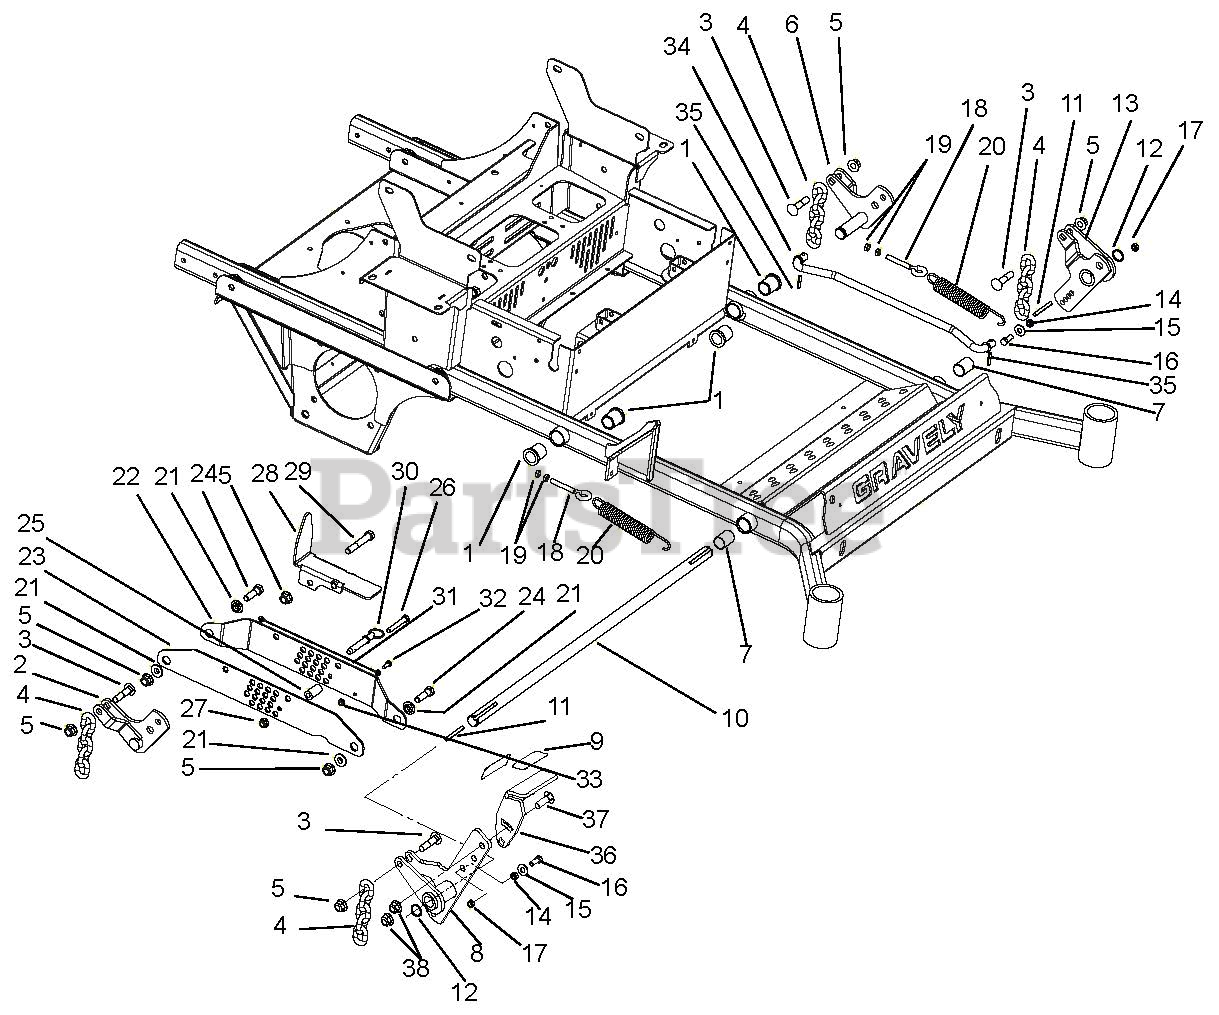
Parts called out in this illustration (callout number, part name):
1	BSHG-FLG 1.00X1.25X1.50X1.50
2	WMT, RH REAR DECK LIFT
3	BLT-RDHDSQNK .50-13X2.25 G5YZ
4	CHAIN, 5 LINK 3/8 MOWER LIFT
5	NUT-LK-NYL-FLG .50-13 YWZC
6	WMT, LH REAR DECK LIFT
7	BSHG,1.00ID X 1.125OD X 1.50LG
8	WMT, ADJUSTABLE DECK FOOT LIFT
9	GRIP, PEDAL 1.50 X 3.00
10	SHAFT, FRONT MOWER LIFT
11	KEY-SQ .25 X 2.50 X .25 SAE
12	RG-RTNG-EXT 1.00X.078
13	WMT, FRONT LH DECK LIFT
14	BSHG-SLV .377X.624X.235
15	WSHR-FL-STL.438X1.00X.083 YWZ
16	BLT-HEX .38-16X1.00 GR5 YWZC
17	NUT-LK-CTR-JAM .375-16 YWZC
18	BLT-EYE .375-16X2.50 YWZC
19	NUT-HEX-JAM .375-16 YWZC
20	SG-TENS .162X1.25X8.25 WLD 25
21	BSHG-FLG .515X.750X.395X1.120
22	RH LIFT/CUT HT BRKT-INBRD-BLK
23	RH LIFT/CUT HT BRKT-OUTBRD-BLK
24	BLT-HEX .50-13X1.75 GR5 YWZC
25	SPACER, .375 X .625 X 1.54
26	BLT-HEX .38-16X2.50 GR5 YWZC
27	NUT-LK-NYL-FLG .38-16 YWZC
28	MECHANICAL LOCK-UP WMT - BLACK
29	BLT-HEX .50-13X3.25 GR5 YWZC
30	PIN,.50 X 2.00 USABLE LG BALL
31	CABLE, 12.0 LANYARD, NYLON
32	BLT-HEX .25-20X.75 GR5 YWZC
33	NUT-LK-NYL-FLG .25-20 YWZC
34	ROD-LIFT ASSIST 19.35"
35	PIN-ROLL .250X1.25 STNLESS STL
36	ADJUSTABLE FOOT LIFT PEDAL-BLK
37	BLT-RDHDSQNK .50-13X1.50 G5YZ
38	NUT-LK-NYL-FLG .50-13 YWZC
